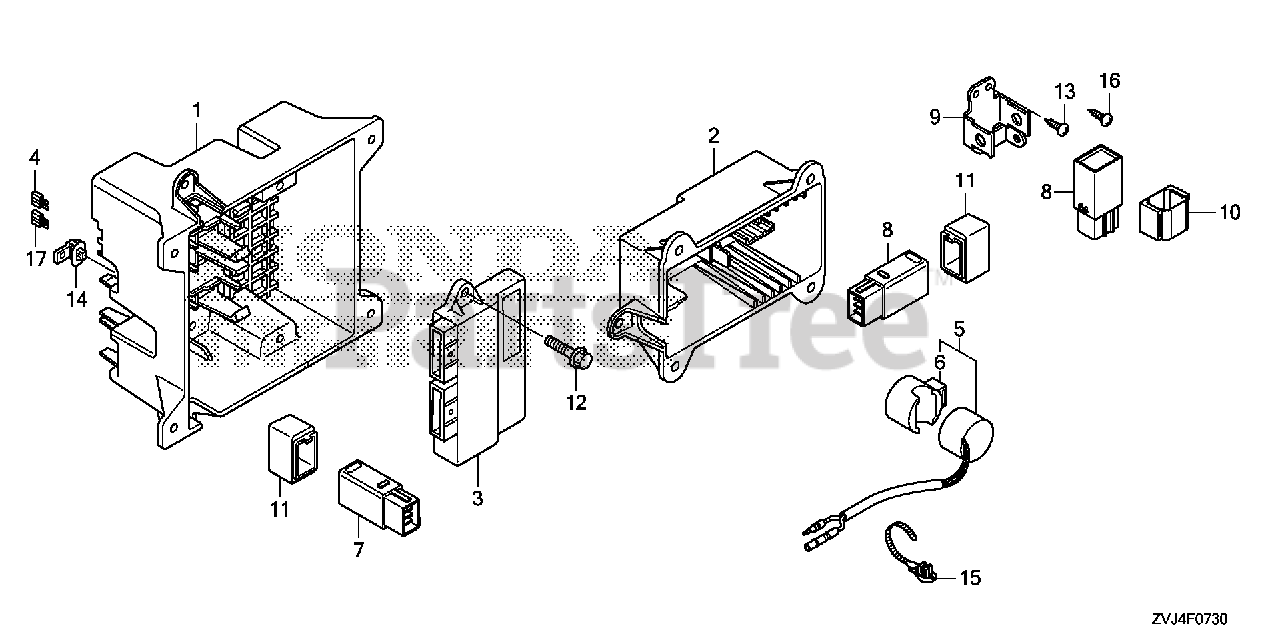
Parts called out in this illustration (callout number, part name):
1	CASE, CONTROL UNIT
3	CONTROL UNIT
4	FUSE, BLADE (3A)
7	RELAY ASSY., MAIN
8	RELAY ASSY., MAIN
9	BRACKET, MAIN RELAY
10	CUSHION, RELAY
11	SUSPENSION, RELAY
12	BOLT, FLANGE (6X20)
13	SCREW, TAPPING (5X16) (PO)
16	SCREW, TAPPING (4X25)
17	FUSE, MINI (5A)
